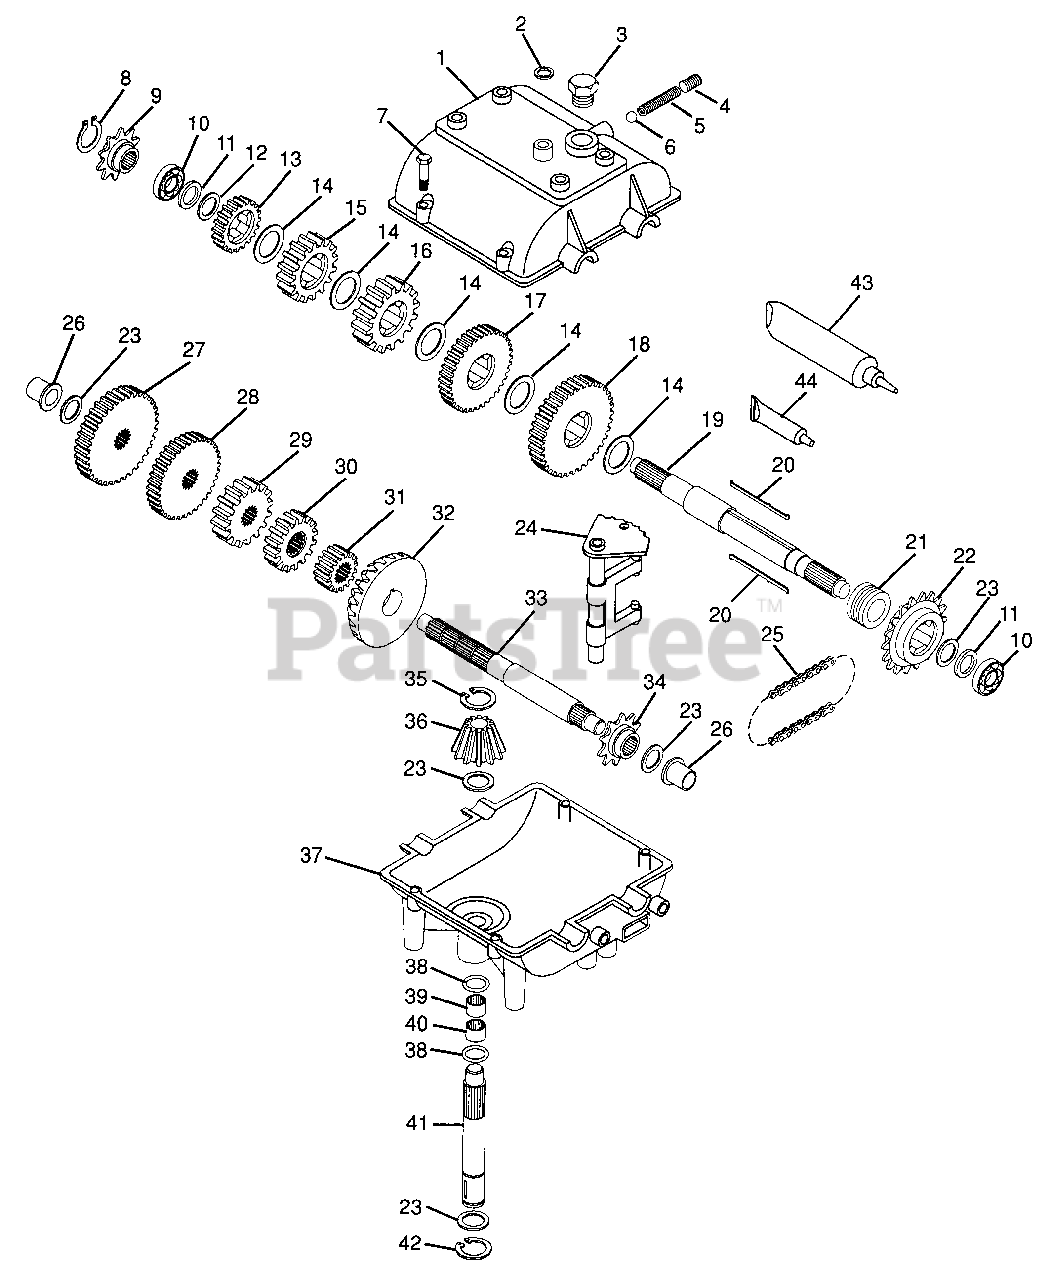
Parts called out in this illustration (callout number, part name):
1	Cover, Transmission
2	Seal, Square Cut
3	Plug, Threaded
4	Screw, Set 3/8-16 x 3/8
6	Ball, Steel 5/16
7	Screw, HHD Taptite 1/4-20 x 1-1/4
8	Ring, Retaining
9	Sprocket (12 Teeth)
10	Bearing, Ball
11	Washer, Thrust
12	Washer, Thrust
13	Gear, Spur (20 Teeth)
14	Washer, Thrust
15	Gear, Spur (22 Teeth)
16	Gear, Spur (25 Teeth)
17	Gear, Spur (30 Teeth)
18	Gear, Spur (35 Teeth)
19	Shaft, Output & Brake
21	Collar, Shift
22	Sprocket (18 Teeth)
23	Washer, Thrust
24	Rod & Fork Assembly, Shift
25	Chain, Roller (No. 41 Chain, 24 Links)
26	Bushing, Flanged
27	Gear, Spur (30 Teeth)
28	Gear, Spur (28 Teeth)
29	Gear, Spur (25 Teeth)
30	Gear, Spur (20 Teeth)
31	Gear, Spur (15 Teeth)
32	Gear, Bevel (42 Teeth)
33	Shaft, Counter
34	Sprocket (9 Teeth)
35	Ring, Retaining
36	Bevel Pinion, Input
37	Case, Transmission
39	Bearing, Needle
40	Bearing, Needle
41	Shaft, Input
42	Ring, Retaining
43	Grease (32 oz. Bottle Bentonite Grease)
44	Gasket Eliminator (Loctite 515)
